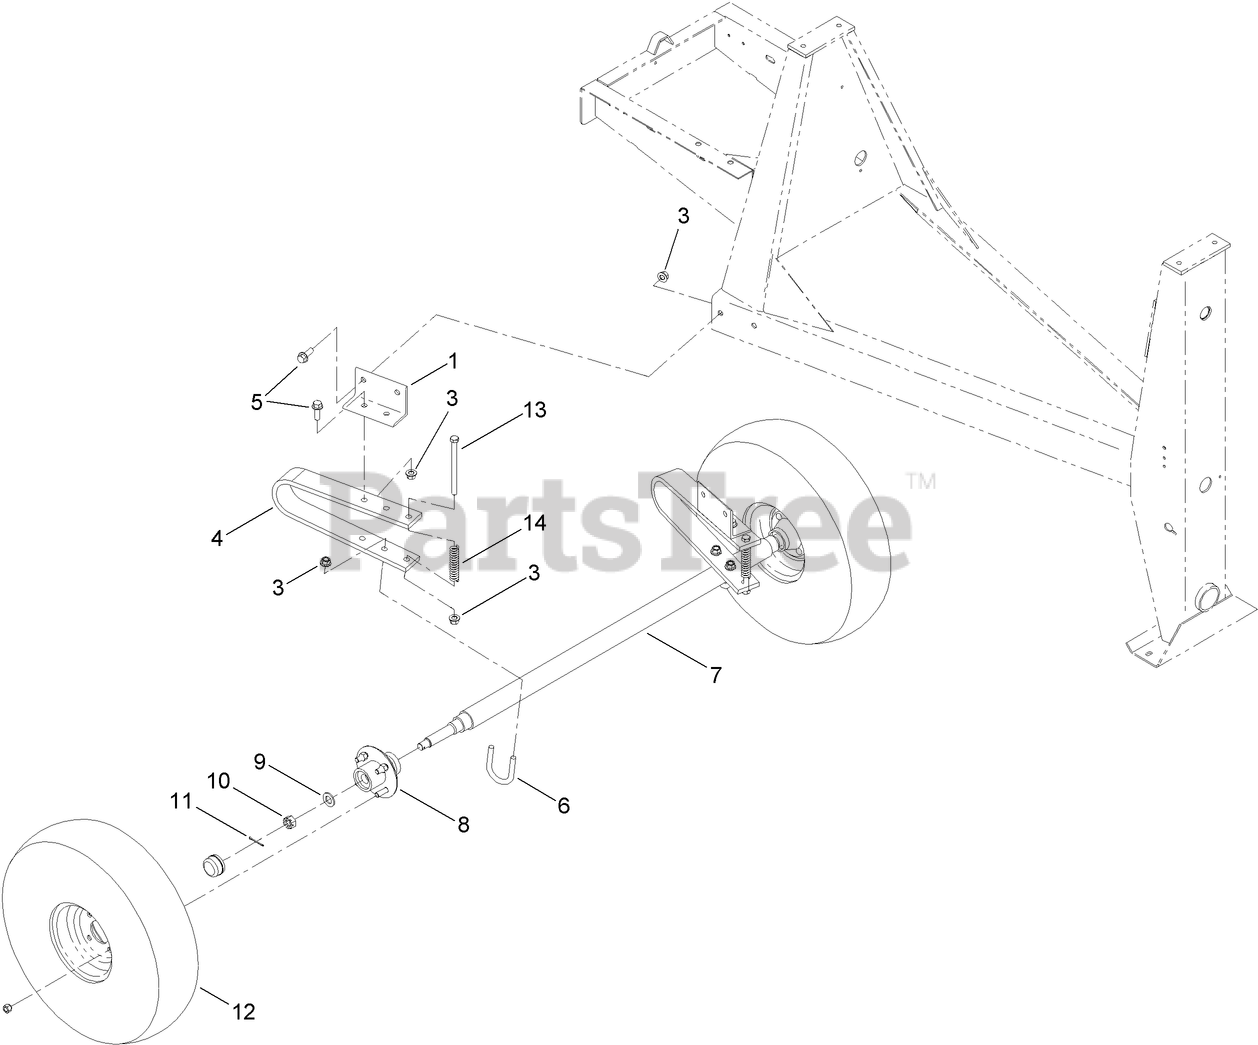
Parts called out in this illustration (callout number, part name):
1	BRACKET-AXLE, SPRING
3	NUT-LOCK
4	SPRING-LEAF
5	SCREW-HHF
6	BOLT-U
7	AXLE-SPRING
8	HUB ASM
9	WASHER-FLAT
11	PIN-COTTER
12	TIRE AND RIM ASM
13	SCREW-HH
14	SPRING-COIL
